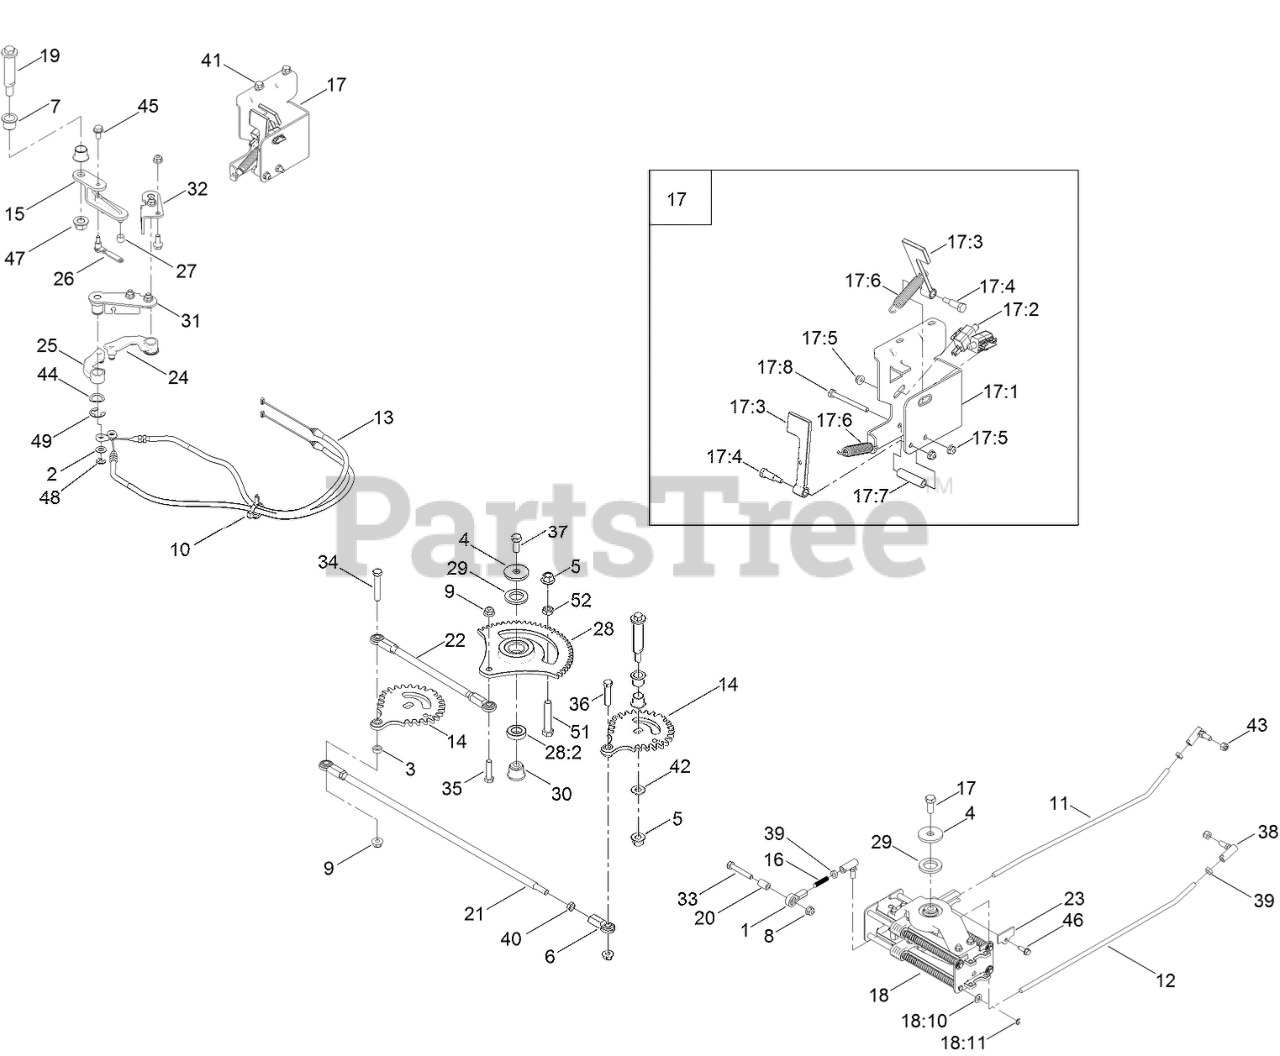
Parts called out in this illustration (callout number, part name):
1	BALLJOINT-RH
2	WASHER-THRUST
3	SPACER
4	WASHER-THRUST
5	NUT-LOCK
6	JOINT-BALL, END
7	BEARING-FLANGE, IGLIDE
8	NUT-HF, NI
9	NUT-HF, NI
10	CLAMP-HOSE
11	ROD-HYDRO, RH
12	ROD-HYDRO, LH
13	CABLE-STEERING
14	GEAR-WHEEL, 30 TOOTH
15	LEVER-CABLE
16	ROD-THREADED
17	NEUTRAL RETURN ASM
17:1	BRACKET-SWITCH
17:2	SWITCH
17:3	ARM-SWITCH
17:4	BOLT-SHOULDER
17:5	NUT-HF
17:6	SPRING-EXTENSION
17:7	SPACER
17:8	SCREW-HH
18	SPEED CONTROL ASM
18:10	WASHER-THRUST
18:11	E-RING
19	BOLT-SHOULDER
20	SPACER
21	ROD-CROSS, NARROW
22	ROD-STEERING, NARROW
23	COVER-END ROD
24	ARM-CABLE, RH
25	ARM-CABLE, LH
26	STRAP-ROLLER
27	BUSHING
28	SECTOR GEAR ASM
28:2	BEARING-BALL
29	SPACER-BEARING
30	PIVOT-BEARING
31	CABLE BRACKET ASM
32	CABLE BRACKET ASM
33	SCREW-HH
34	SCREW-HH
35	SCREW-HH
36	SCREW-HH
37	SCREW-HH
38	BALLJOINT-RH (W/GROMMET)
39	NUT-JAM
40	NUT-HJ
41	SCREW-HHF
42	WASHER-FLAT
43	NUT-LOCK
44	WASHER-BOWED
45	SCREW-HWHTF
46	SCREW-HWH, THREAD ROLL
47	SCREW-HWHTF
48	RING-RETAINING
49	E-RING
51	SCREW-HH
52	NUT-JAM
